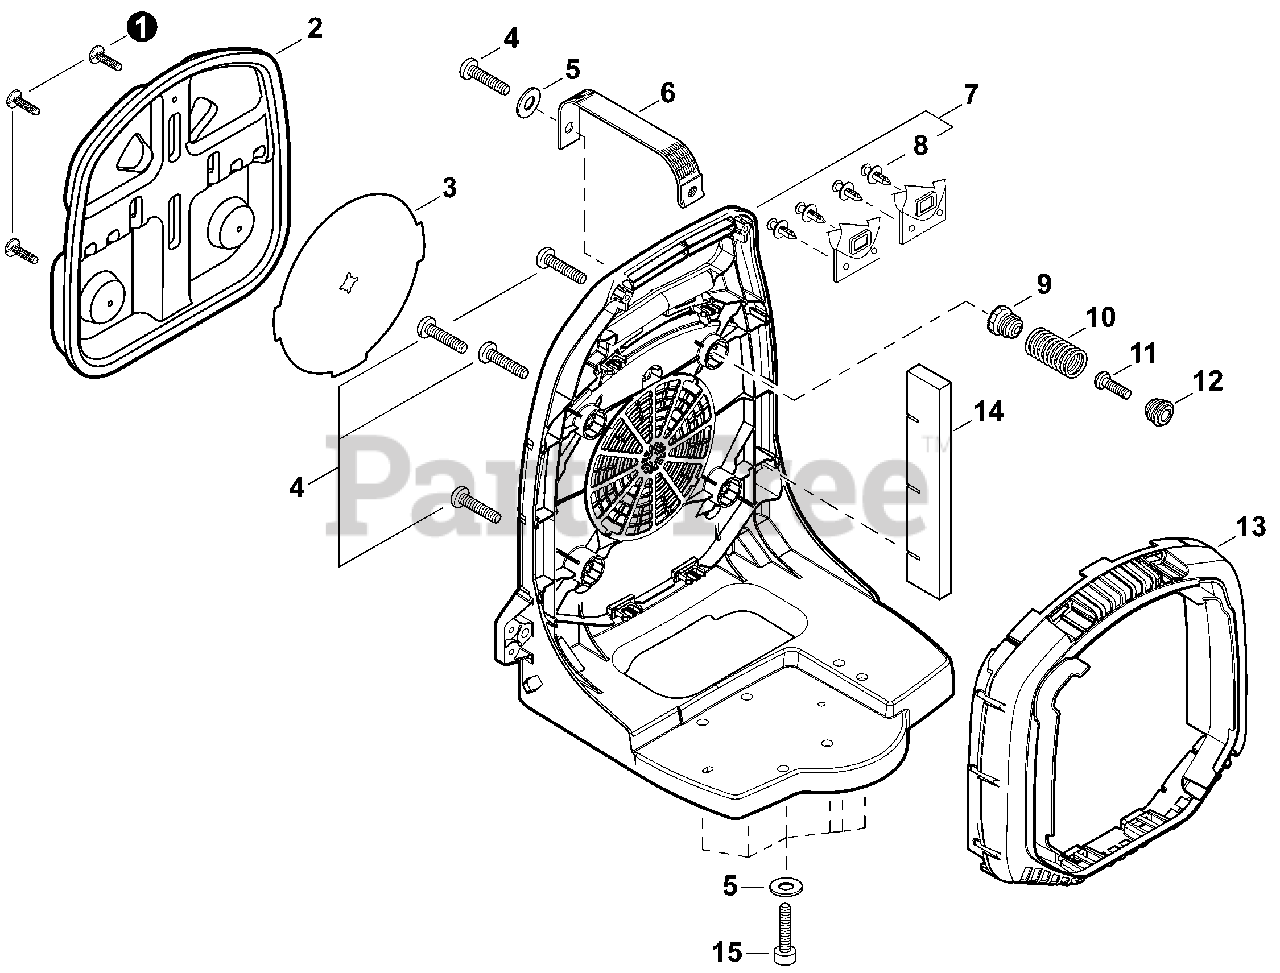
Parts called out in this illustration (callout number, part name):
2	CUSHION, BACKPACK
3	INSERT, COLD WEATHER
4	BOLT, TORX 5×20
5	WASHER 5.5×16×2T
6	STRAP, SAFETY 1.2×100
7	FRAME, BACKPACK WITH CLIPS
9	HOLDER, SPRING
10	SPRING, COMPRESSION
11	BOLT, TORX 5×16
12	HOLDER, SPRING
13	GUARD, DEBRIS
14	PAD, FOAM
15	SCREW 5×25
